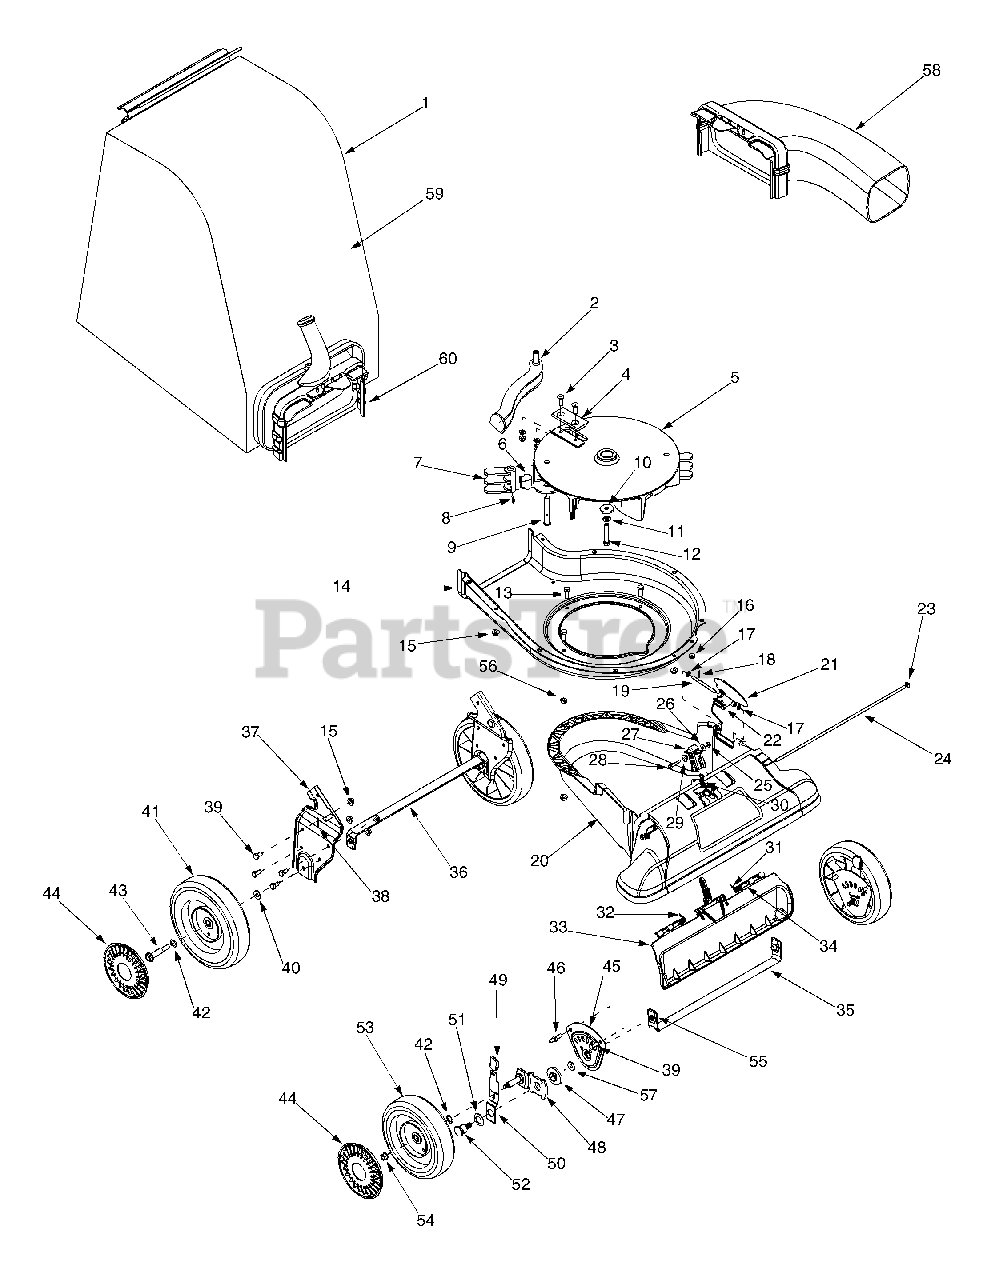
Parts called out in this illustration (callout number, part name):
1	Bag Assembly
3	Hex Screw 5/16-24 x 1.0
4	Chipper Blade
5	Impeller Assembly
6	Pin Clip
7	Flail Blade
8	Spiral Pin
9	Clevis Pin
10	Flat Washer.375 ID x 1.25 OD
11	Lock Washer 3/8
12	Hex Cap Screw 3/8-24 x 2.0
13	Hex Cap Screw 5/16-18 x .875
15	Flange Lock Nut 5/16-18
16	Hex Flange Nut 1/4-20
17	Flat Washer .281 ID x .50 OD
18	Cotter Pin
19	Pivot Rod
20	Nozzle
21	Base Adapter Door
22	Torsion Spring
23	Cap Speed Nut 1/4
24	Pivot Rod
25	Hex Lock Nut #10-24
26	Flat Washer .194 ID x .62 OD
27	Nozzle Door Lever
28	Hex Screw #10-24 x 1.25
29	Shoulder Spacer
30	Extension Spring
31	Torsion Spring LH
32	Torsion Spring RH
33	Nozzle Door
34	Rod .25 x 1.25 Lg
38	Cotter Pin
39	Hex Cap Screw 5/16-18 x.625
40	Bell Washer.401 ID x.870 OD
41	Wheel 9 x 2
42	Wave Washer .531 ID x .781 OD
43	Shoulder Screw 3/8-16
44	Hubcap
47	Height Adjustment Bearing
48	Pivot Arm Assembly
49	Height Adjustment Knob
50	Spring Lever
51	Bell Washer .760 ID x .25 OD
52	Shoulder Screw .750 ID x .625 OD
53	Wheel 8 x 2
54	Flange Lock Nut 3/8-16
55	Lock Nut 3/8-16
56	Hex Lock Nut 5/16-18
57	Thrust Washer .375 ID x .70 OD
58	Blower Chute
59	Bag
60	Chute Assembly
